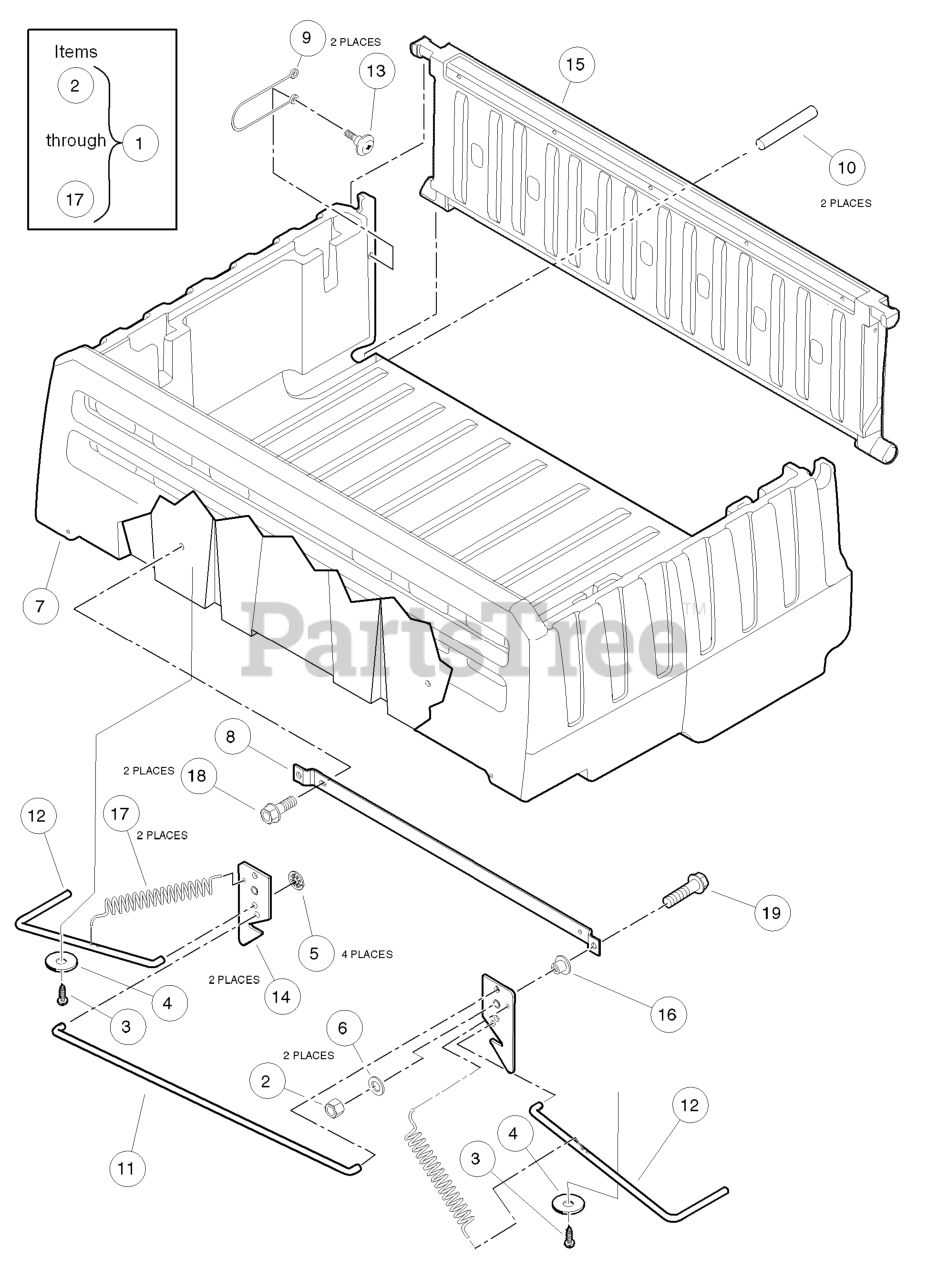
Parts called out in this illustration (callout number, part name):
1	BED ASM - 4200 SERIES
2	LOCKNUT, DIMPLED
3	SCREW, HEX WASH
4	WASHER, 5/16 TYPE B FLAT
5	PUSHNUT, 3/8
6	Washer, 3/8 Flat Type A
8	Support, Latch Link
9	LANYARD, TAILGATE
10	Pin, Support
11	Rod, Long Link
12	Rod, Bed Lift, Short Bent
13	BOLT LANYARD
14	Catch, Tilt Bed
15	TAILGATE, HUSQVARNA
16	Bearing, Bronze, 1/2x9/32
17	Spring, Tilt Latch 3.4 Lb/in
19	SCREW, CAP, HEX HD 3/8-16X1.00
